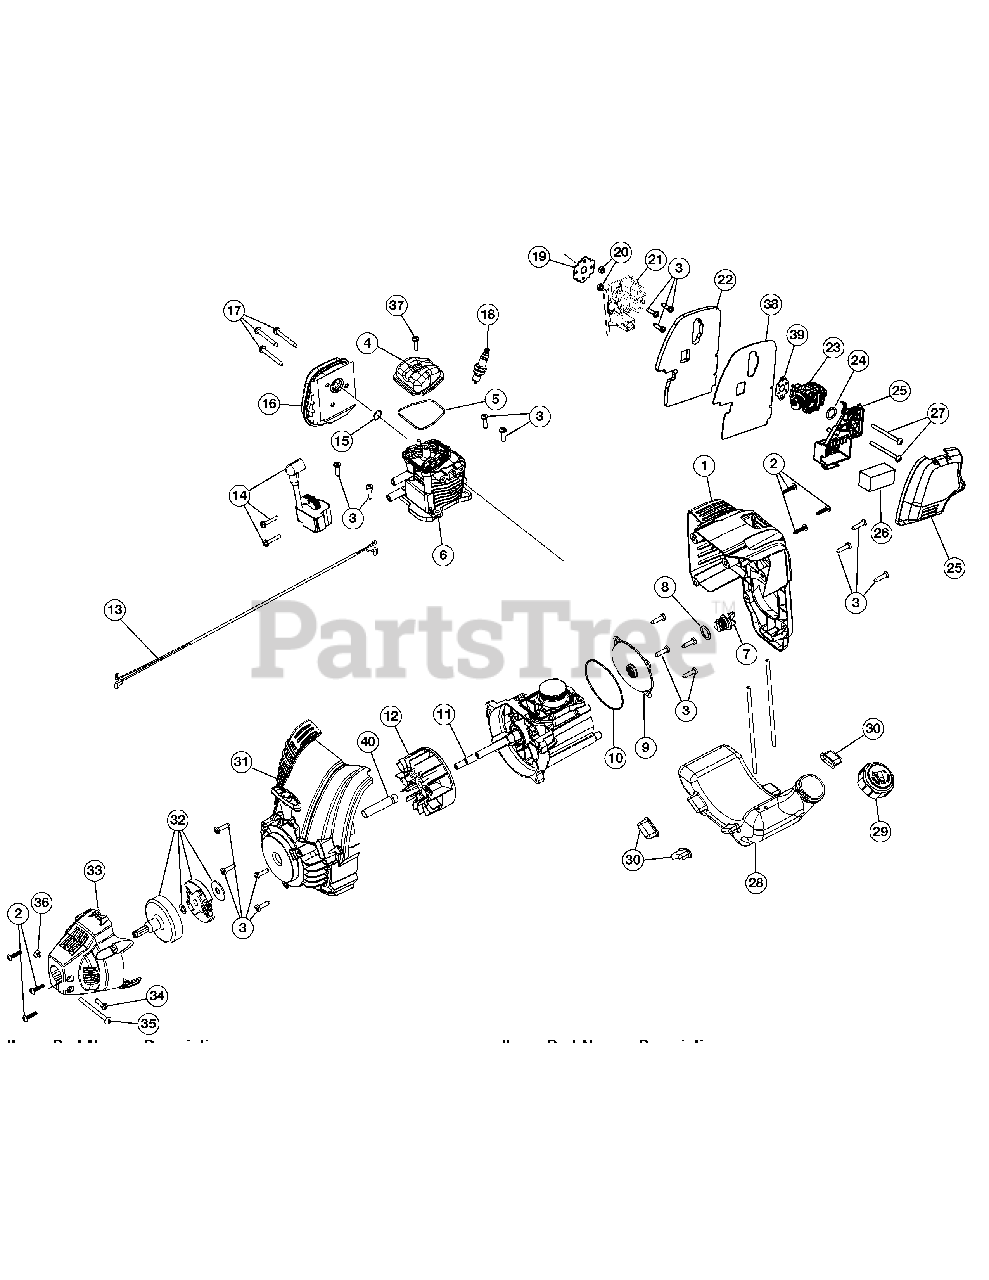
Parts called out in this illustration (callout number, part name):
1	Engine Cover Assembly (Incl. 2 & 3)
2	Cover Screw
4	Rocker Cover
5	Rocker Cover O-Ring
6	Cylinder Assembly (Incl. 3 & 5)
7	Oil Plug (Incl. 8)
8	Oil Plug O-Ring
9	Crankcase Cover
10	Crankcase Cover O-ring
11	Crankcase Assembly (Incl. 10)
12	Flywheel Assembly
13	Lead Wires
14	Module Assembly
15	Muffler Gasket
16	Muffler Assembly (Incl. 15 & 17)
17	Muffler Screw
18	Spark Plug
19	Insulator Gasket
22	Heat Shield
23	Carburetor
25	Air Cleaner Cover Assembly (Incl. 26)
26	Air Filter
28	Fuel Tank Assembly w/Fuel Lines (Incl. 29)
30	Fuel Tank Pads
31	Starter Housing Assembly (Incl. 3)
32	Clutch Assembly
33	Clutch Cover (Incl. 2)
34	Anti-Rotation Screw
35	Clamp Screw
37	Rocker Cover Screw
